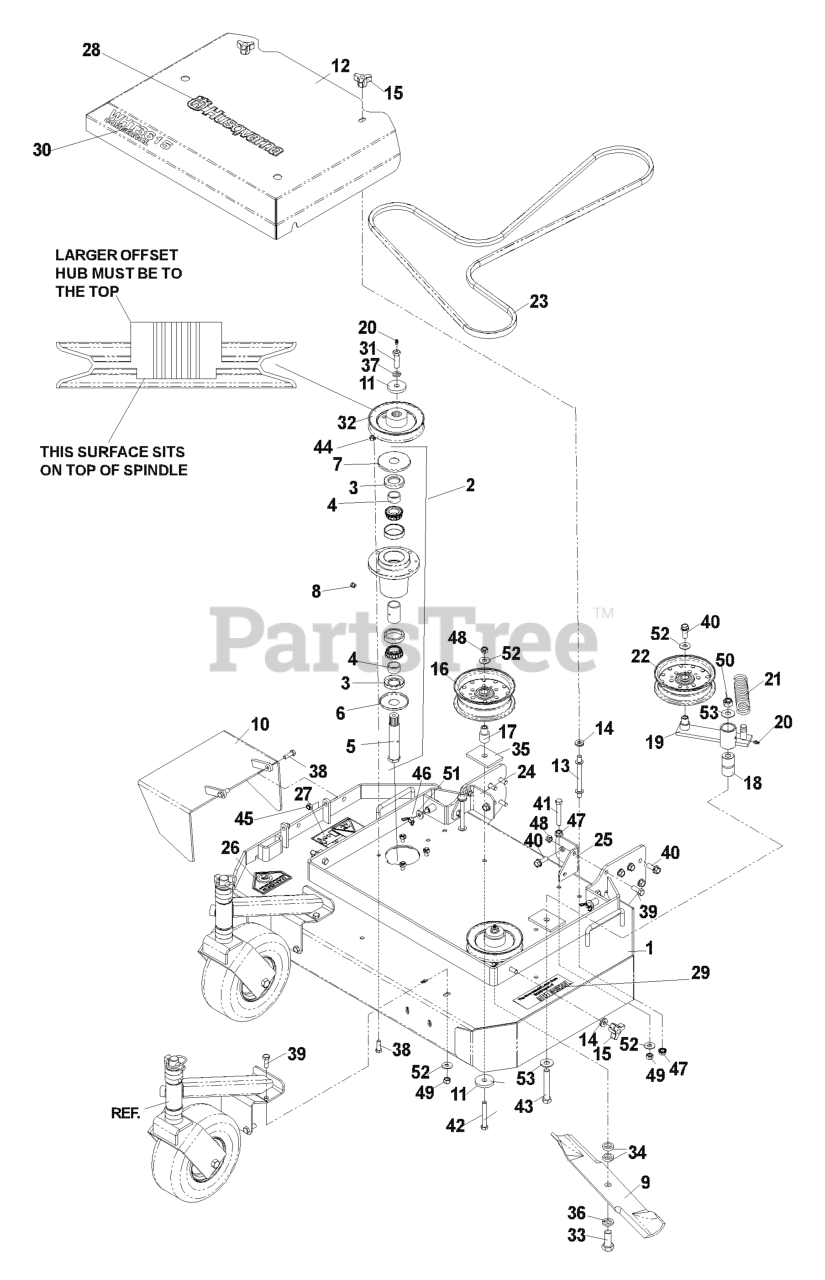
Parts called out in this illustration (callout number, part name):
1	DECK W/DECALS 36"WSL
2	SPINDLE ASSY - 52/61"
3	SHAFT SEAL
5	52/61 SPINDLE - SPLINED SHAFT
6	BOTTOM DUST CAP
7	TOP DUST CAP
8	PLUG-VENTED
9	BLADE OEM 18"
10	DEFLECTOR CHUTE
11	SPINDLE WASHER
12	BELT SHIELD, 36" ORANGE
13	SHIELD SPACER
14	WASHER, 3/8 SEALING
15	KNOB, THREE PRONG
16	IDLER PULLEY (TALL)
17	IDLER BUSHING
18	PIVOT BUSHING
20	ZERK
22	IDLER PULLEY
24	DECK SLIDE, RT
25	DECK SLIDE, LT
26	DECAL, CPSC
27	DECAL, EURO SEVERING
28	DECAL, HUSQVARNA 12"
29	DECAL, NASCAR
30	DECAL, WTH3615
31	DRILLED BOLT 7/16-20 X 1 1/2"
32	PULLEY - 52"
33	HCS 5/8-18X1-1/2 GR5 TPBLT ZD
34	BLADE SPACERS
36	LOCKWASHER 5/8
37	WASHER 7/16 LOCK
38	HCS 5/16C X 1
39	HCS 3/8-16X1.GRD.5.ZD
40	4CS 3/8C X 1 SERRATED HEAD
41	HCS 3/8C X 2 1/2
42	SCREW 3/8C X 2 3/4 HEX CAP
43	HCS 1/2C X 3 1/4
44	NUT 5/16C CENTERLOCK
45	NUT 5/16 NYLOC
46	WINGNUT, 5/16C NYLOC
47	NUT 3/8C WHIZ
48	NUT 3/8C CENTERBLOCK
49	NUT 3/8-16 NYLOC
50	NUT 1/2-13 HEX NYLOC ZD
51	WASHER 5/16 FLAT
52	WASHER 3/8 FLAT
53	WASHER 1/2 FLAT
